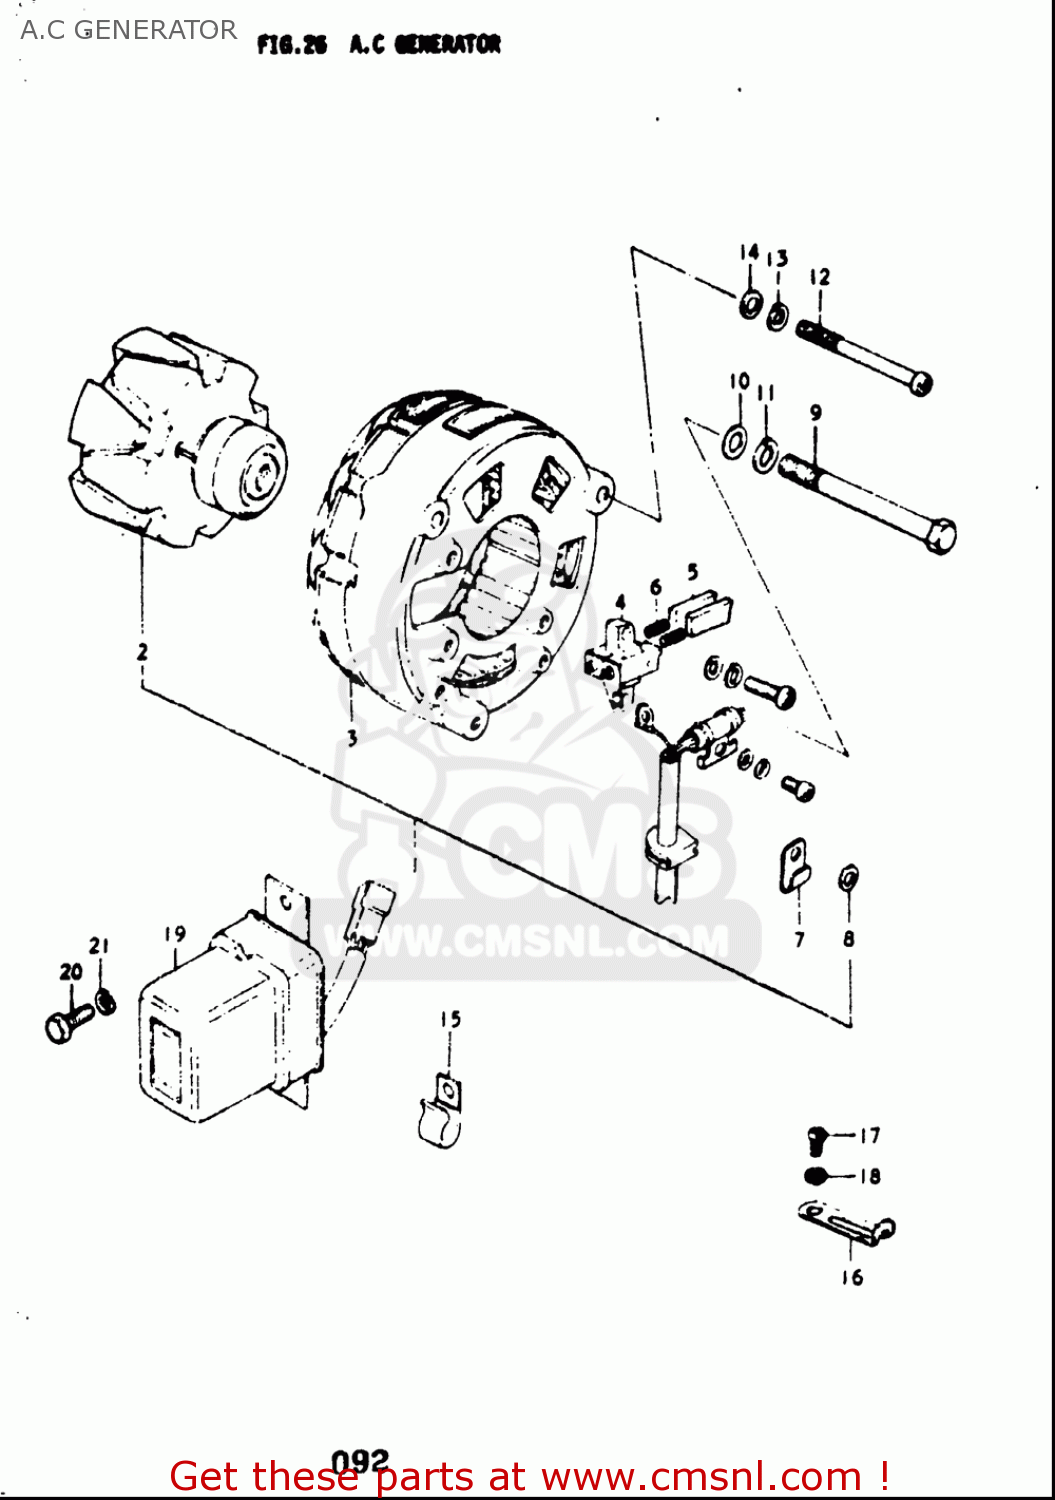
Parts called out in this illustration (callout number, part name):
5	BRUSH
6	SPRING
10	WASHER (8.2X22X3.2)
11	WASHER,LOCK
12	SCREW 5X65 CROS
13	WASHER,LOCK
14	WASHER
15	CLAMP
16	CLAMP(L:120 T:1.0)
17	SCREW
18	WASHER,LOCK
19	REGULATOR ASSY,VOLTAGE
20	BOLT
21	WASHER,LOCK
